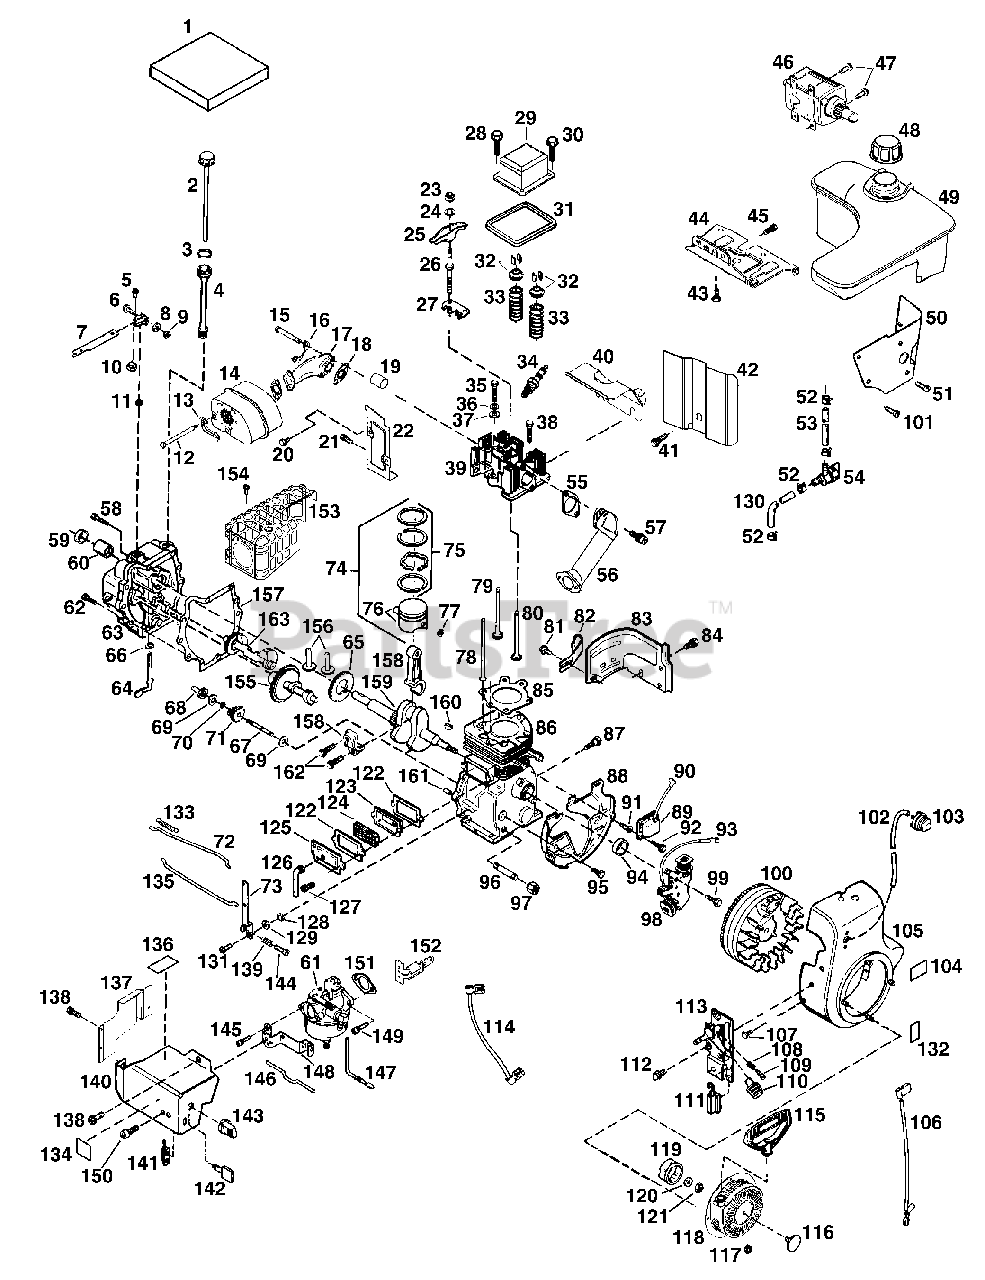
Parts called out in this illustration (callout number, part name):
1	Gasket Set
4	Oil Fill Tube
5	Screw, Torx T-15, 8-32 x 3/8"
6	Screw, 10-32 x 3/4"
7	Governor Lever
8	Lock Washer
9	Lock Nut, 10-32
10	Lock Nut, 10-32
11	Retaining Ring
12	Screw, 5/16-18 x 4-1/2"
13	Locking Plate
15	Screw, 5/16-18 x 1-9/32"
16	Locking Plate
17	Exhaust Manifold
18	Exhaust Gasket
19	Exhaust Port Liner
20	Screw, Torx T-30, 1/4-20 x 1/2".
21	Lock Nut, 10-32
22	Blower Housing Extension
24	Lock Washer
25	Rocker Arm
26	Rocker Arm Stud
27	Push Rod Guide
28	Valve Cover Mounting Stud
29	Rocker Arm Cover
30	Screw, Torx T-30, 1/4-20 x 1/2"
31	Rocker Arm Cover Gasket
32	Valve Spring Keeper
33	Valve Spring
34	Spark Plug (RN4C)
35	Screw, 5/16-18 x 2-1/2"
36	Belleville Washer
38	Screw, Torx T-30, 1/4-20 x 15/32"
39	Cylinder Head
40	Cylinder Head Cover
41	Screw, 10-32 x 1/2"
42	Heat Baffle
43	Screw, 1/4-15 x 3/4"
44	Fuel Tank Bracket
45	Screw, 5/16-18 x 7/8"
46	Electric Starter Motor (110 Volt)
47	Screw, Torx T-30, 1/4-20 x 15/32"
48	Fuel Cap
49	Fuel Tank
50	Fuel Tank Extension
51	Screw, 10-32 x 1/2"
52	Fuel Line Clamp
53	Fuel Line
54	Fuel Shut-Off Valve
55	Intake Pipe Gasket
56	Intake Pipe
57	Screw, Torx T-30, 5/16-18 x 7/8"
58	Screw, 1/4-20 x 1-3/16"
60	Crankshaft Bushing
61	Carburetor
62	Screw, 1/4-20 x 1-11/16"
63	Cylinder Cover
64	Governor Rod
65	Counterbalance Gear
66	Governor Yoke
67	Governor Shaft
68	Governor Spool
70	Retaining Ring
71	Governor Gear Ass’y
72	Governor Link
73	R.P.M. Adjusting Lever
74	Piston, Pin & Ring Set (Std.)
75	Ring Set (Std.)
76	Piston & Pin Ass’y (Std.)
77	Piston Pin Retaining Ring
79	Exhaust Valve (Std.)
80	Intake Valve (Std.)
81	Screw, 10-24 x 3/16"
82	Fill Tube Clip
83	Blower Housing Extension
84	Screw, Torx T-30, 1/4-20 x 1/2"
85	Cylinder Head Gasket
86	Cylinder
87	Screw, 1/4-20 x 1/2"
88	Blower Housing Baffle
89	Solid State Ignition
90	Spark Plug Cover
91	Solid State Mounting Stud
92	Screw, Torx T-15, 10-24 x 15/16"
95	Screw, 1/4-20 x 5/8"
96	Oil Drain Extension
97	Extension Cap
98	Alternator Coil (18 Watt)
99	Screw, 1/4-20 x 3/4"
100	Flywheel (W/Ring Gear)
101	Screw, 12-16 x 5/8"
102	Primer Line
103	Primer Ass’y
104	Primer Decal
105	Blower Housing
106	Ground Wire
107	Screw, Torx T-40, 5/16-24 x 21/32"
108	Compression Spring
109	Screw, Torx T-10, 5-40 x 7/16"
110	Control Knob
112	Screw, 10-32 x 1/2"
113	Control Bracket
114	Ground Wire
115	Starter Handle
116	Starter Decal
117	Nut & Lock Washer, 1/4-28
118	Rewind Starter
119	Cylinder Head Gasket
120	Lock Washer
121	Flywheel Nut
122	Valve Cover Gasket
123	Breather Body
124	Breather Element
125	Valve Cover
126	Breather Tube
127	Screw, 10-24 x 1/2"
130	Fuel Line
131	Screw, 10-32 x 5/8"
132	Instruction Decal
133	Extension Spring
134	Caution Decal
135	Throttle Link
136	Warning Decal
137	Carburetor Cover
138	Screw, 10-32 x 1/2"
139	Compression Spring
140	Carburetor Cover (Front)
142	Key Switch
143	Choke Knob
144	Screw, Torx T-10, 6-32 x 41/64"
145	Screw, 10-32 x 1/2"
146	Choke Spring
147	Choke Rod
148	Choke Bracket
149	Screw, 1/4-20 x 27/32"
150	Screw, 10-32 x 1/2"
151	Carburetor To Intake Pipe Gasket
152	Key Switch Bracket
153	Heat Shield
154	Screw, 10-32 x 5/16"
155	Camshaft (MCR)
156	Valve Lifter
157	Cylinder Cover Gasket
158	Connecting Rod Ass’y
159	Crankshaft
160	Flywheel Key
161	Dowel Pin
162	Connecting Rod Bolt
163	Counterbalance Weight
